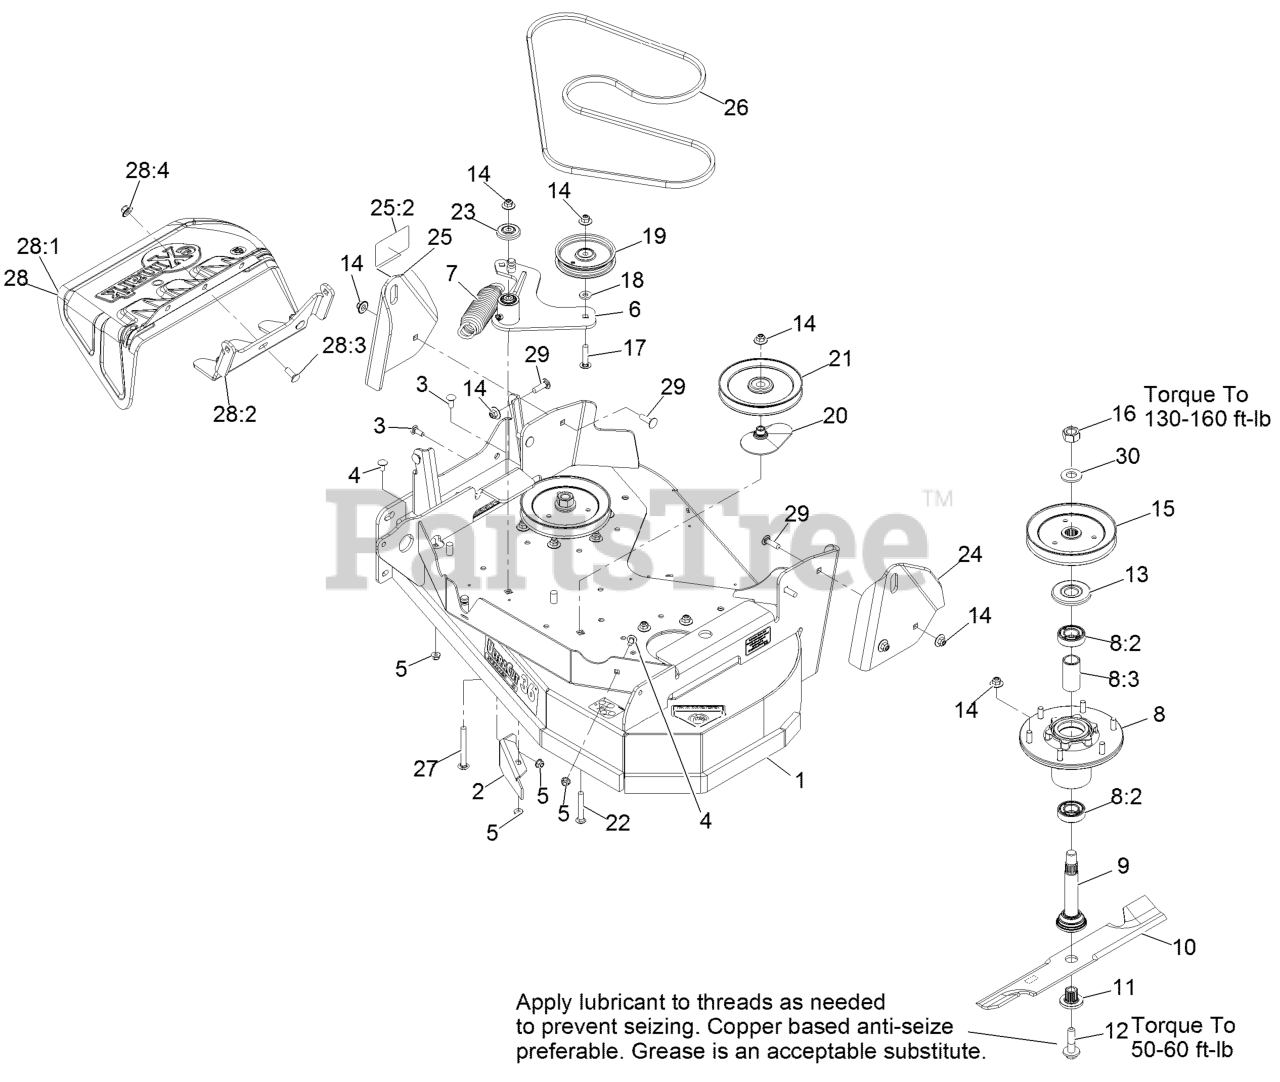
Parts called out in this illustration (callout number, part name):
1	DECK ASM - 36
2	BAFFLE-DOGLEG
3	SCREW-CARR
4	SCREW-CARR
5	NUT-HF, NI
6	IDLER ARM ASM -
7	SPRING-EXTENSION
8	ASM-CUTTER HSG WITH BEARINGS
8:2	BEARING-BALL
8:3	SPACER-BEARING
9	ASM-SPINDLE AND SEAL
11	BUSHING,SPLINED
12	SCREW,SEMS 1/2-20 X 2.19
13	GUARD,BEARING TOP .989
14	Nut-Nyloc 3/8-16 Flg
15	SHEAVE,BLADE DRIVE 6.50
16	NUT-HEX
17	SCREW-CARR
19	PULLEY-IDLER
20	SPACER-PULLEY
21	PULLEY-IDLER
22	SCREW-CARR
23	GUARD-TOP
24	PUSH-TOWER,LH 36
25	PUSH TOWER-RH 36, W/DECAL
25:2	DECAL-WARNING, DISCHARGE
26	BELT-V
27	BOLT-SHOULDER, CARRIAGE 3/8-16 X 3 1/2
28	CHUTE - DISCHARGE ASM
28:1	CHUTE,DISCHARGE
28:2	BRACKET-CHUTE, DISCHARGE
28:3	SCREW-CARR
28:4	Nut-Nyloc 3/8-16 Flg
29	Bolt-Carriage 3/8-16 X 1 1/4
